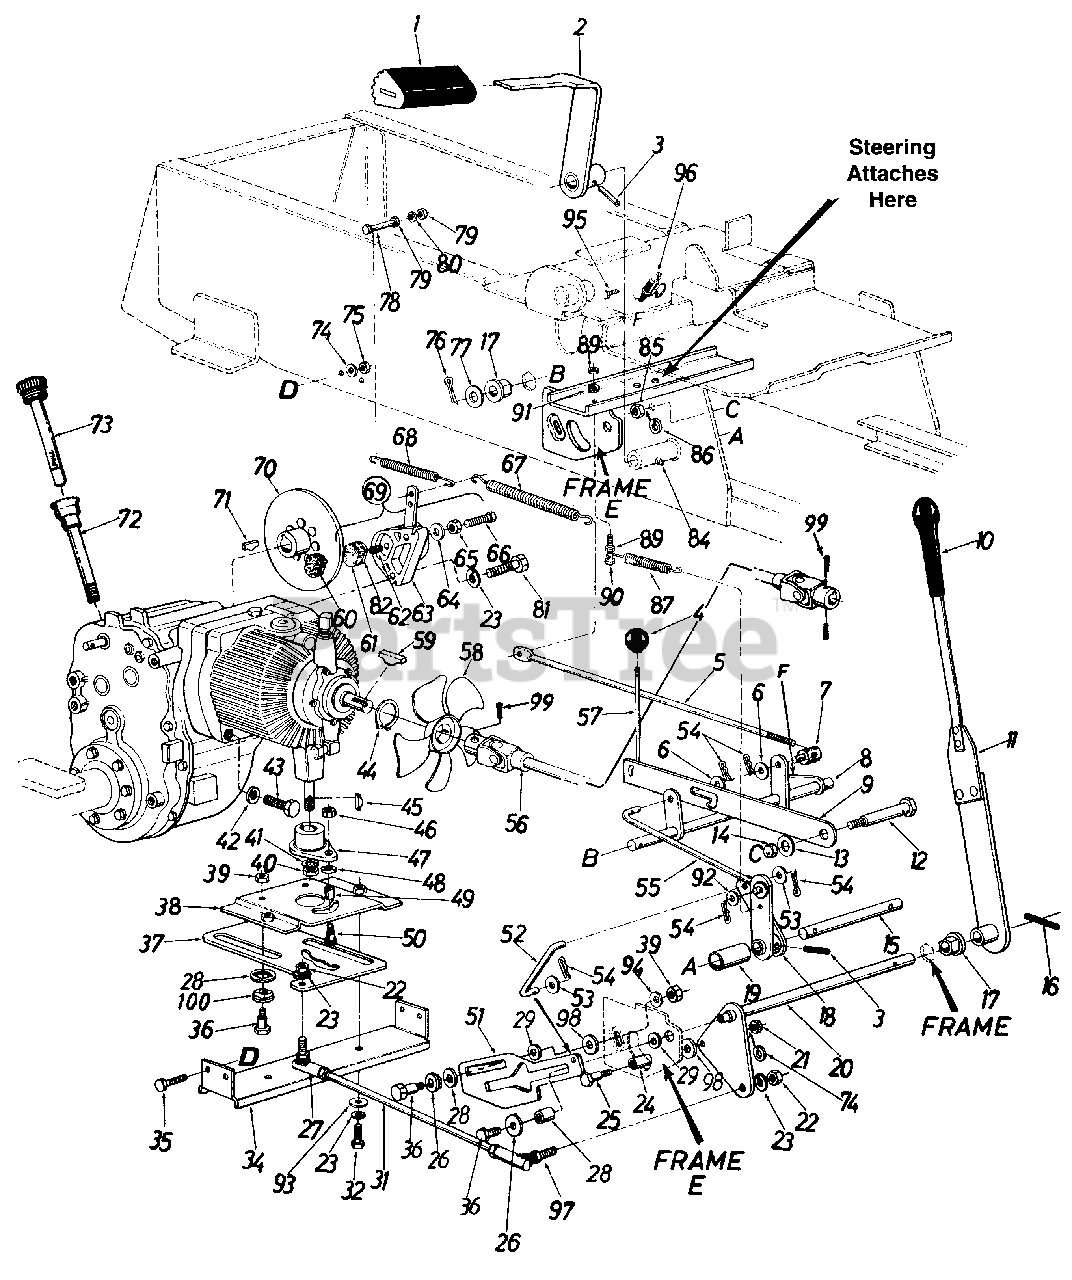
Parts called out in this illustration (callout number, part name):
1	Foot Pad
4	Ball Knob-Brake
5	Brake Rod
6	Fl-Wash. .375" I.D. x 1.00" O.D. x .030"
7	Ferrule
8	Brake Transfer Shaft Assembly
9	Parking Brake Cam
11	Control Arm Assembly Comp.
12	Shld. Bolt .62" Dia. x 2.75" Lg.
13	Fl-Wash. .460" I.D. x 1.24" O.D. x .06"
14	Push Speed Nut for .625" Dia. Shaft
15	Brake Pivot Shaft
16	Spring Pin Spiral 1/4" Dia. x 1.50"
17	Hex Flange Brg. Plastic .62" I.D.
18	Brake Lever Assembly
19	Spacer
20	Control Handle Shaft Assembly
21	Hex Cent. L-Nut 5/16-18 Thd.
22	Hex Nut 3/8-24 Thd.
23	L-Wash. 3/8" I.D.
24	Spacer
25	Shoulder Bolt
26	Fl-Wash. 7/16" I.D. x 1-3/8" O.D.
27	Ball Joint Assembly 3/8-24 Thd.-L.H.
28	Spacer
29	Fl-Wash. .325" I.D. x 1.25" O.D.
31	Tie Rod
32	Hex Bolt 3/8-16 x .75" Lg.
34	Support Channel
35	Hex Bolt 5/16-18 x .75" Lg.
36	Shld. Bolt .437" Dia. x .268"
37	Cam Plate
38	Slide Mtg. Plate Assembly
39	Hex L-Nut 5/16-18 Thd.
40	Hex Nut 1/2-13 Thd.
41	L-Wash. 1/2" I.D.
42	Fl-Wash. .385" I.D. x .87" O.D. x .060"
43	Socket Hd. Scr. 3/8-16 x 2.75" Lg.
44	Snap Ring
45	#5 Hi-Pro Key 1/8" x 5/8" Dia.
46	Hex Cent. L-Nut 1/4-20 Thd.
47	Pintle Plate Assembly
48	Fl-Wash. .281" I.D. x .50" O.D. x .063"
49	Needle Brg .31" I.D. x .50" O.D. x .437"
50	Shld. Bolt .31" Dia. x .500
51	Neutral Control Slide
52	Neutral Control Rod
53	Fl-Wash. .312" I.D. x .630" O.D. x .063"
54	Hairpin Cotter
55	Brake Link Rod Assembly
56	Universal Drive Shaft Comp.
57	Parking Brake Link
58	Fan Assembly
59	#61 Hi-Pro Key 3/16 x 5/8" Dia.
60	Lining-Brake
61	Lining-Brake
62	Actuator Pin
63	Housing with Lever and Pin
65	Nut
66	Adjustment Pin
67	Extension Spring .50" O.D. x 6.5"
68	Extension Spring (Brake Return)
69	Disc Brake Assembly Comp.
70	Brake Disc Assembly
71	Hi-Pro Key 3/16 x 3/4" Dia.
72	Dipstick Tube Assembly
73	Dipstick Assembly
74	L-Wash. 5/16" I.D.
75	Hex Nut 5/16-18 Thd.
76	Cotter Pin 1/8" Dia. x 1.00" Lg.
77	Fl-Wash. .635" I.D. x 1.00" O.D. x .120"
78	Hex Scr. 1/4-20 x 2.50" Lg.
79	Hex Nut 1/4-20 Thd.
80	L-Wash. 1/4" I.D.
81	Hex Bolt 3/8-16 x 1.25" Lg.
82	Backing Plate
84	Grease Fitting
85	Hex Nut 7/16-20 Thd.
86	L-Wash. 7/16" I.D.
87	Extension Spring
89	Hex Nut 1/4-20 Thd.
90	Hex Bolt 1/4-20 x 1.25" Lg.
91	L-Wash. 1/4" I.D.
92	Fl-Wash.
93	Fl-Wash. .38" I.D. x 1.25" O.D.
94	Bell-Wash.
95	Hex Bolt 1/4-20 x .5" Lg.
96	Safety Switch
97	Ball Joint Assembly 3/8-24 Thd.-R. H.
98	Fl-Wash. .32" I.D. x .6" O.D.
99	Set Screw 5/16-18 x .38" Lg.
100	Thrust Washer
